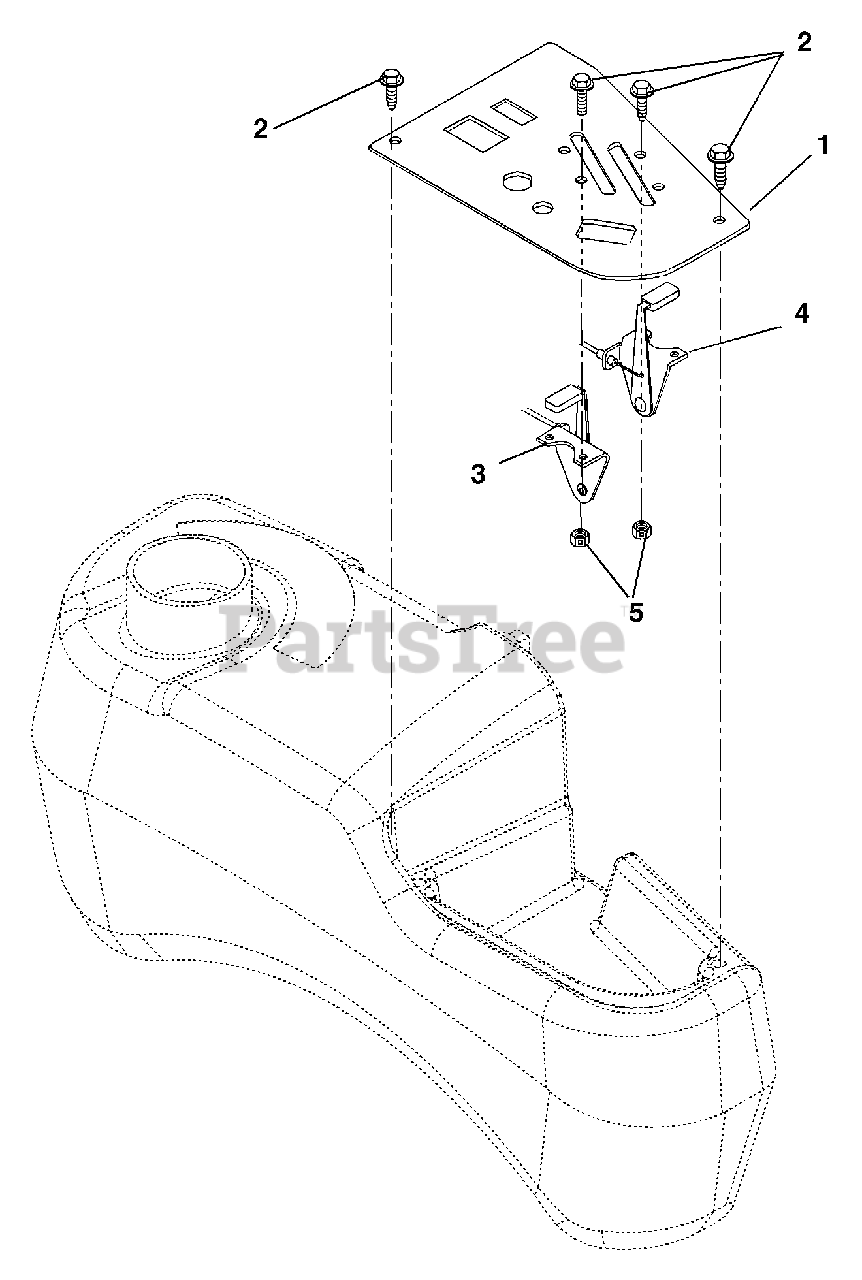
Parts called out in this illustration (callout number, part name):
1	CONTROL PANEL - BLACK
2	@SCR-MCH 10-24X.50 HWH YWZC
3	CABLE, THROTTLE
4	CABLE, CHOKE W/STR LEVER
5	@NUT-LK-NYL 10-24 W/INSRT YWZC
